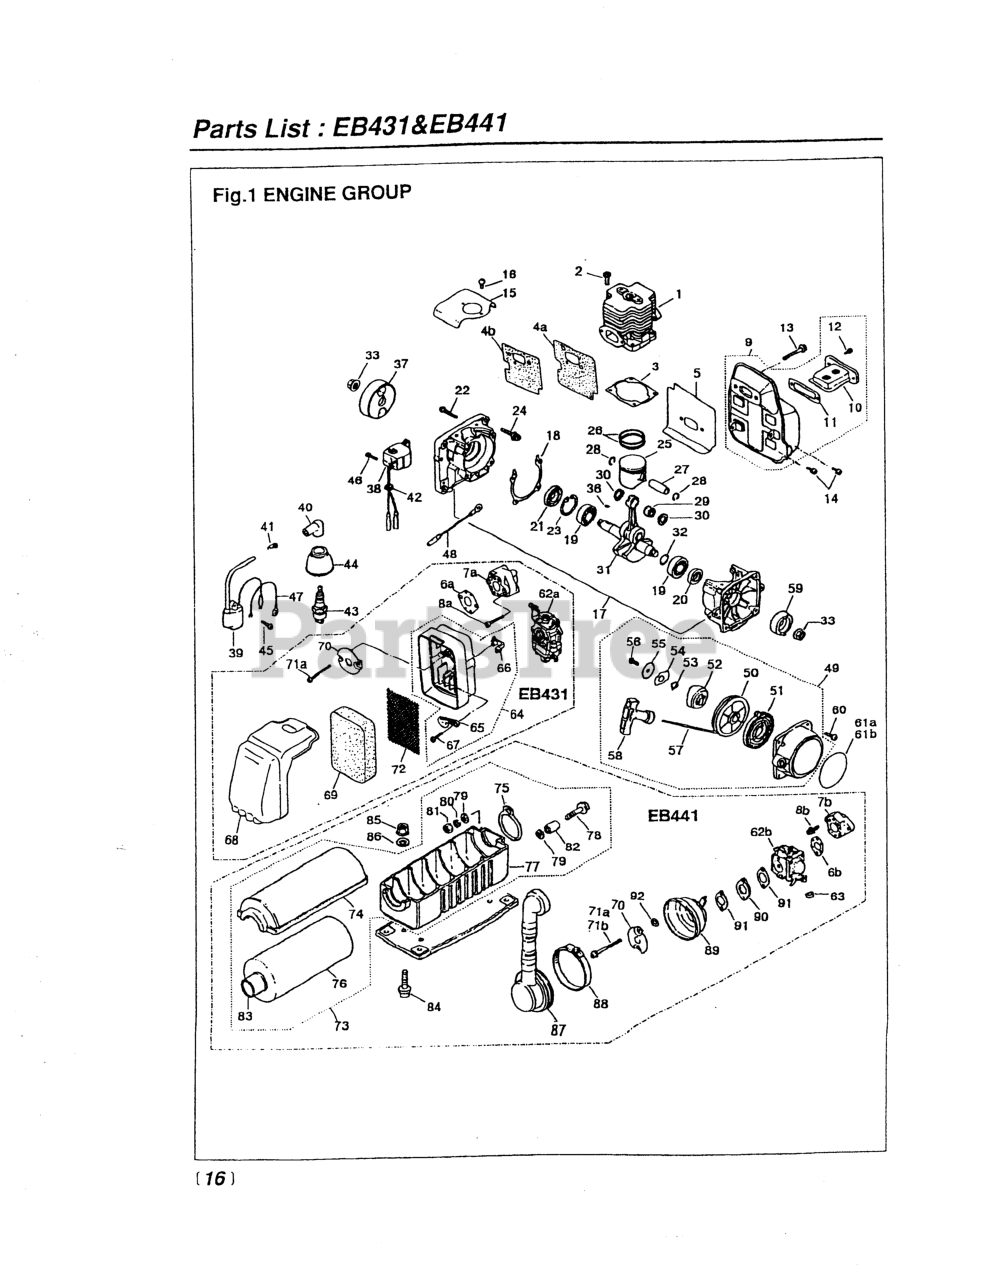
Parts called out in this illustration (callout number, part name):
1	CYLINDER (RPLS -12111)
7B	INSULATOR (RPLS-14112)
9	MUFFLER (RPLS -15101)
10	ARRESTER
12	SCREW, M4 x 10
17	CRANKCASE
20	SEAL, OIL - STARTER SIDE
22	BOLT, M5 X 30
23	RING, SNAP, M35 X 1.5
26	RING, PISTON (RPLS -41210)
27	PIN, PISTON (RPLS. 1490-41316)
28	RING, SNAP
29	BEARING
30	WASHER (RPLS 1491-41510)
31	SHAFT (RPLS -42001)
32	SHIM (REPLACES 848-870-G000)
33	NUT, M10
36	KEY
39	COIL, IGNITION
41	SPRING
42	GROMMET
44	CAP (NO LONGER AVAILABLE)
45	SCREW, M4 x 16
46	BOLT, M4 X 16
47	CABLE COMPLETE
51	SPRING (RPLS -75220)
52	DOG
54	RETAINER (RPLS 1861-75161)
55	WASHER
56	SCREW
57	ROPE
58	KNOB
59	PULLEY (RPLS -75210)
60	BOLT, M5 x 20
63	CAP, CABLE END
70	PLATE (REPLACES -82511)
71B	SCREW, M5 X 55
73	CLEANER, AIR
74	COVER, CLEANER
75	BAND
76	ELEMENT
77	CASE, CLEANER
79	WASHER, M5 X .8
80	WASHER, SPRING M4 x 1.3
81	NUT, M5 X 4
82	COLLAR (NLA)
84	SCREW, M5 x 16
85	NUT (B)
86	WASHER, M5 X .8
87	HOSE (RPLS -83300)
88	CLAMP
89	CASE, CLEANER
NI	KIT, GASKET
